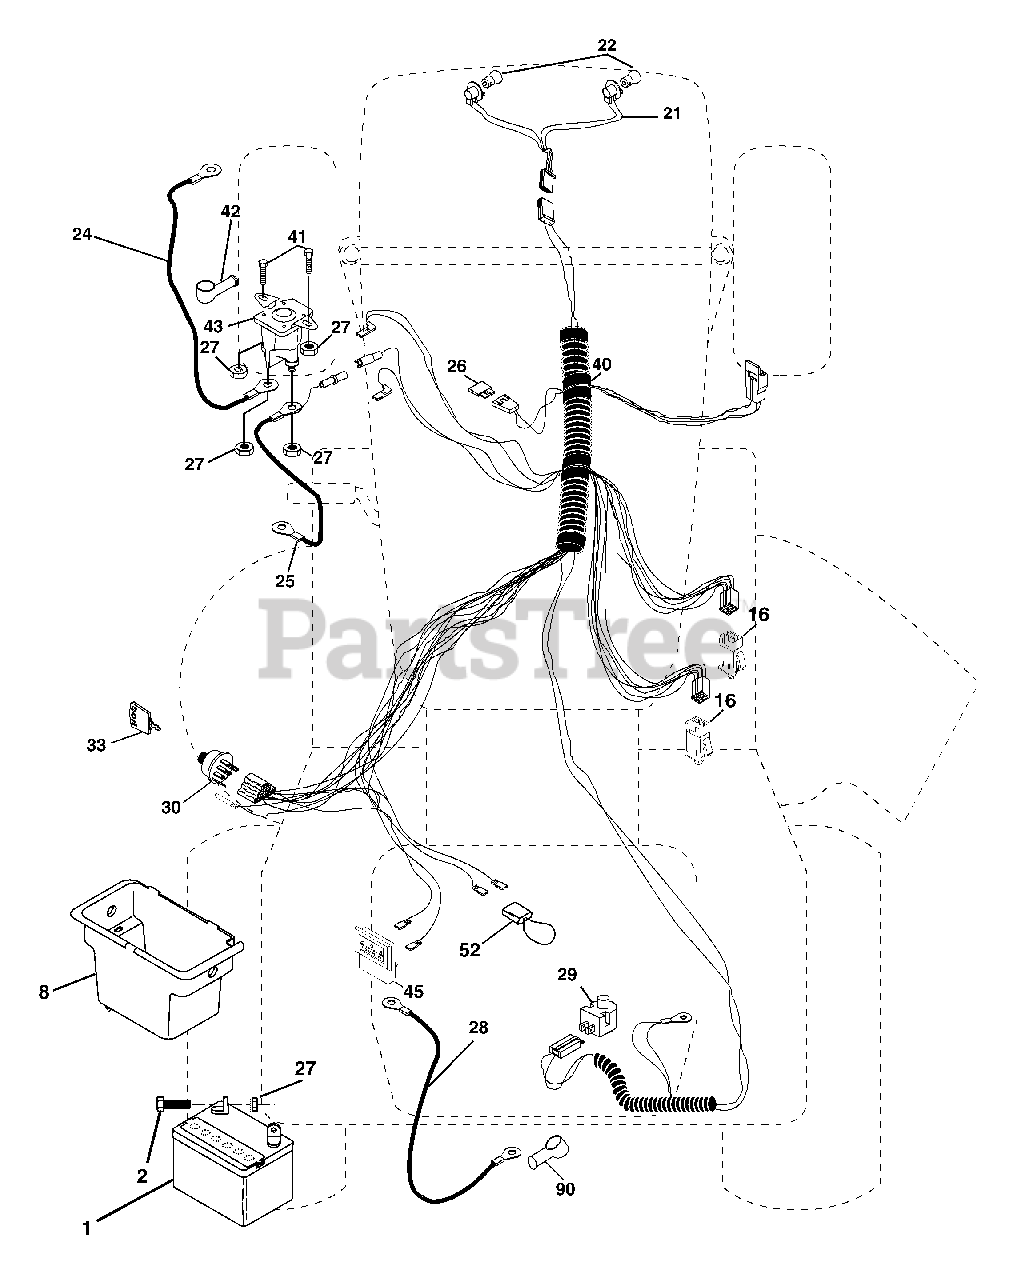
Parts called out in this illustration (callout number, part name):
1	Battery
2	Bolt Hex Hd 1/4-20unc X 3/4
8	Box Battery Fender
16	Switch Interlock
21	Harness Socket Light
22	Bulb, Light #1156
24	Cable Battery
25	Cable Battery 6 Ga Red w/16 wire
26	Fuse
27	Nut Keps Hex 1/4-20 Unc
28	Cable Ground 6ga 12 black
29	Switch Plunger Nc Gray
30	Switch Ign
33	Key Ign Molded Generic
40	Harness Ign
41	Bolt Fin Hex 1/4-20 unc x 1/2
42	Cover Terminal Red
43	Solenoid
45	Ammeter Rectangular
52	Protection Loop
90	Cover Terminal Battery
